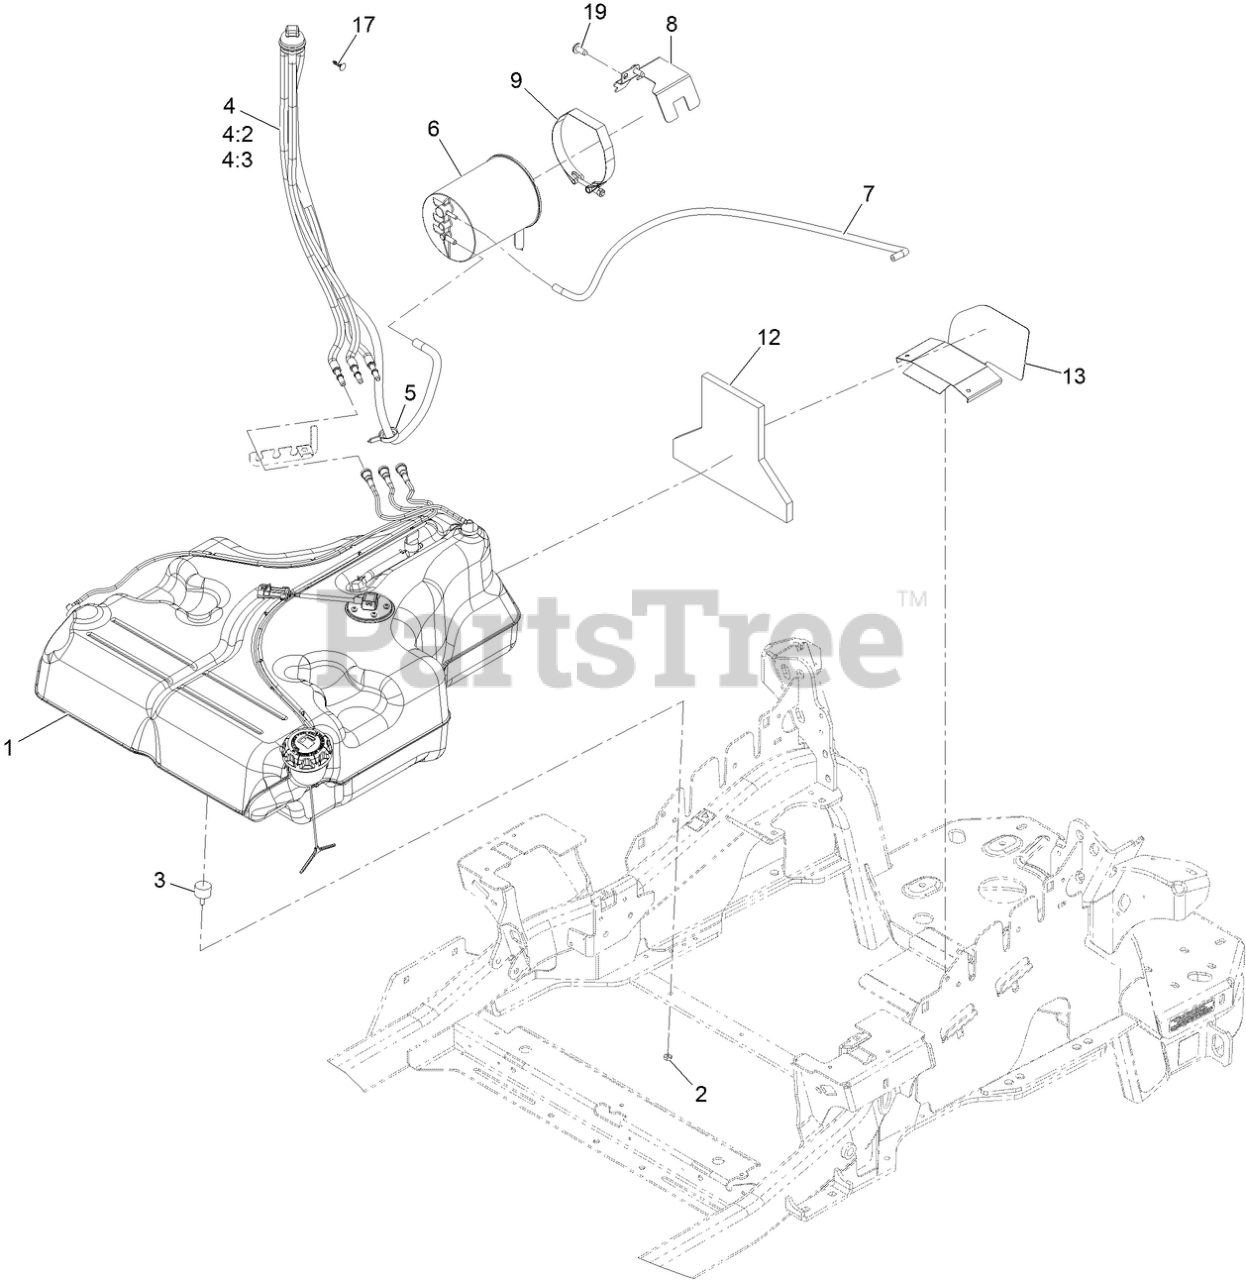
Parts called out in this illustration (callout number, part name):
1	FUEL TANK ASM
2	NUT-JAM
4	FUEL MANIFOLD VENT ASM
4:2	HOSE-FUEL
4:3	HOSE-FUEL
5	CLAMP-HOSE
6	CANISTER-CARBON, 1200CC
7	HOSE-FUEL
8	Mount-Canister
9	CLAMP, T-BOLT
12	INSULATION-FOAM, FUEL TANK
13	GUARD-EXHAUST
17	PLUG-PLASTIC
